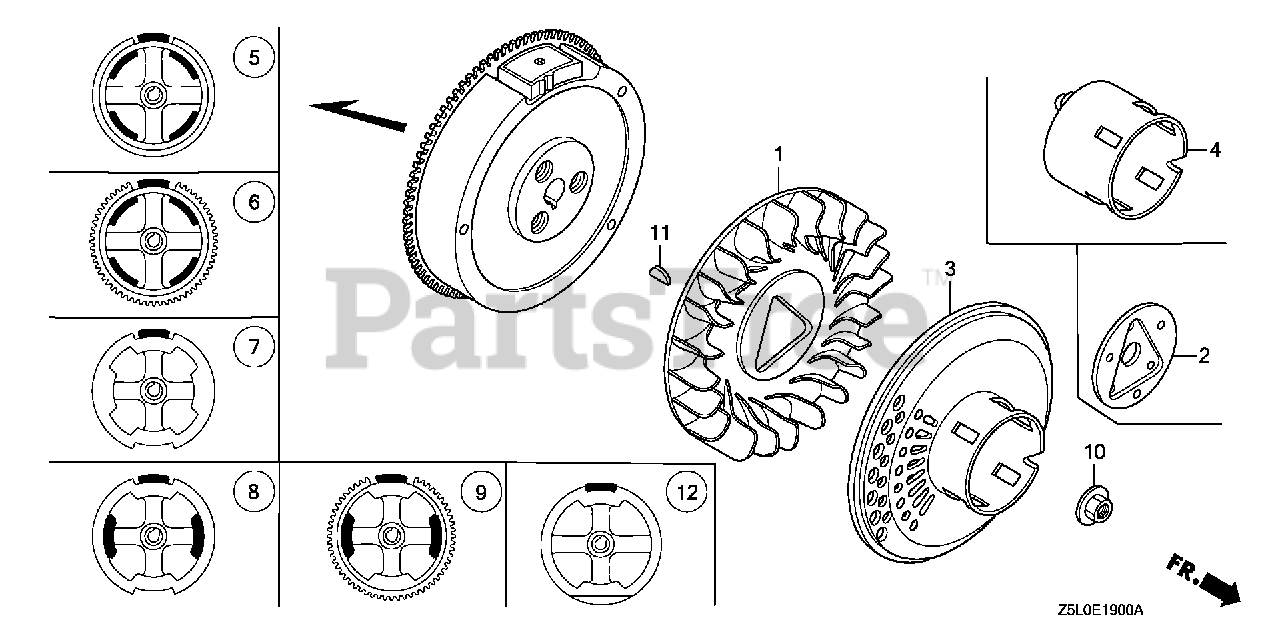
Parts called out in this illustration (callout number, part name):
1	FAN, COOLING
3	PULLEY, STARTER (SCREEN GRID)
10	NUT, SPECIAL (16MM)
11	KEY, SPECIAL WOODRUFF (25X18)
